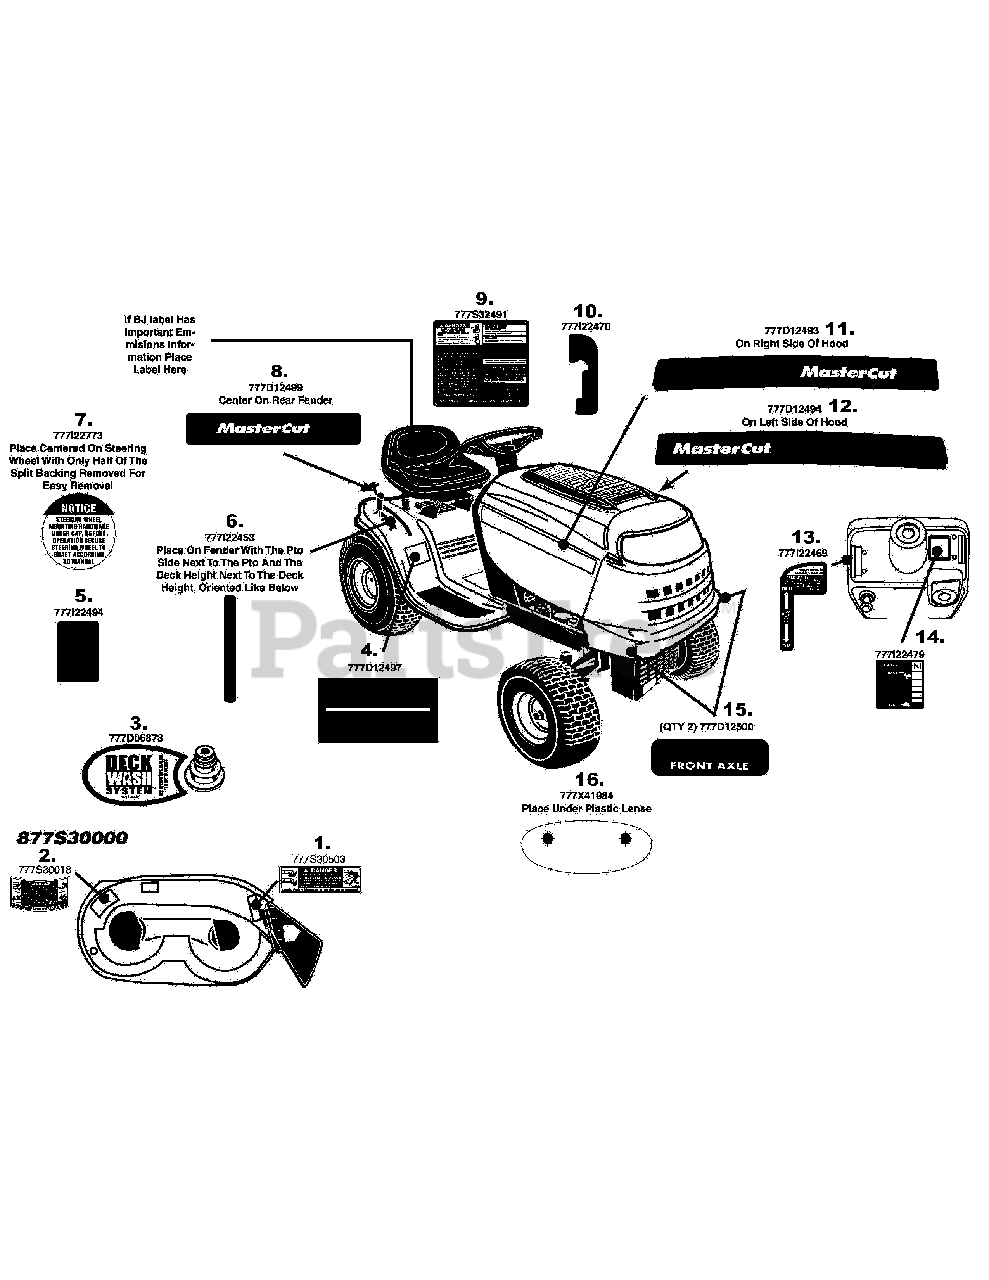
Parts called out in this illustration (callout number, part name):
1	LABEL-DANGER CHUTE
2	LABEL-DECK SAFETY
3	LABEL-DECK
4	LABEL-RIDER RUNNING BOARD 42" HYDR
5	LABEL:LT-5 TRANS RELEASE
6	LABEL:RIDER LT-5 FENDER
7	LABEL-RIDER:SECURE WHEEL
8	LABEL-RIDER RH FENDER MASTERCUT
9	LABEL:RIDER:SAFETY LT-5
10	LABEL:RIDER:LT-5 FENDER HYDRO
11	LABEL:RIDER:HDSD:MASTERCUT HYD:RH
12	LABEL:RIDER:HDSD:MASTERCUT HYD:LH
13	LABEL: RIDER LT-5 DASH HYDRO
14	LABEL: RIDER LT-5 THRT/CHK
15	LABEL-RIDER LOWER HOOD CAST IRON
16	LABEL:RIDER 1&5 STYLE GRILL
